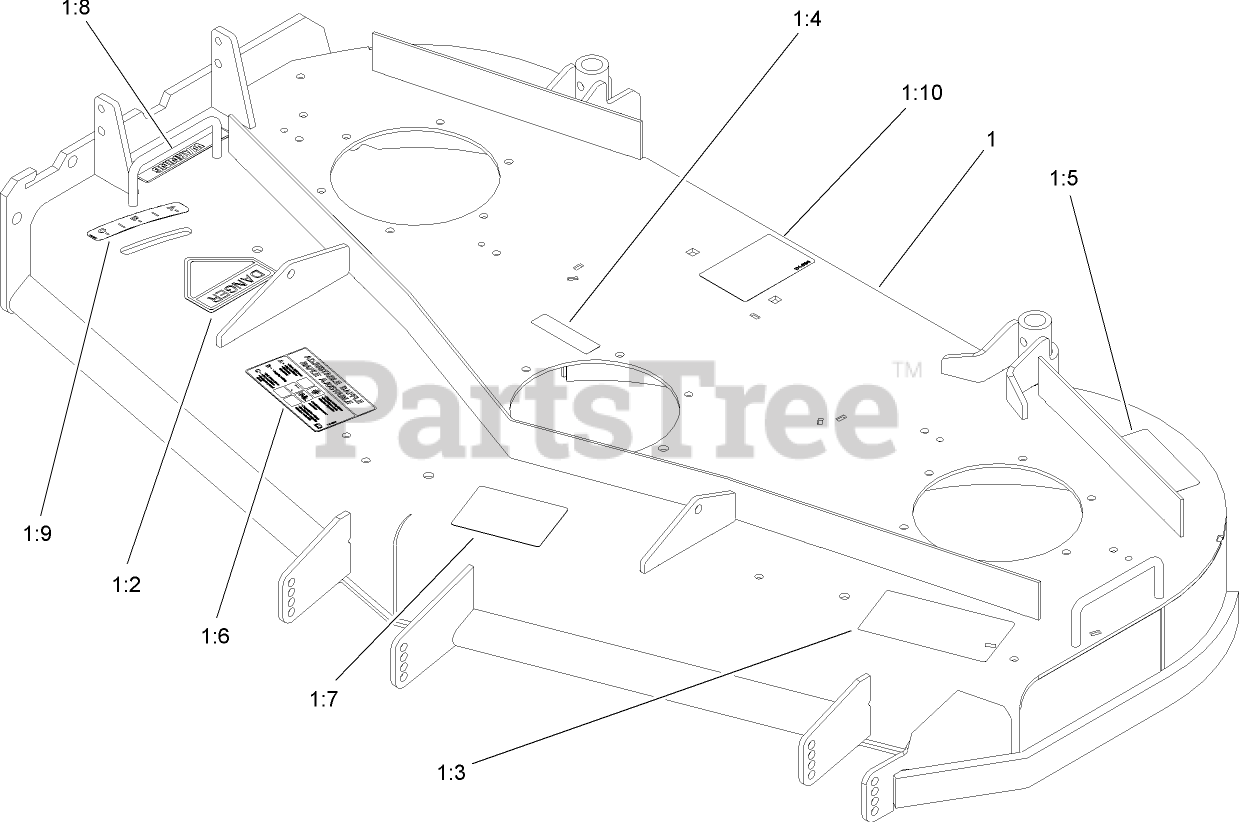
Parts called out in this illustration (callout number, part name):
1	52 INCH DECK ASM
1:2	DECAL-DANGER
1:3	DECAL-DANGER, THROWN OBJECT
1:4	DECAL-COVER, MISSING
1:5	DECAL-TORQUE
1:6	DECAL-ADJUSTMENT, BAFFLE
1:7	DECAL-SCALP, ANTI
1:8	DECAL-WARNING
1:9	DECAL-SETTING, BAFFLE
1:10	DECAL-ROUTING, BELT
